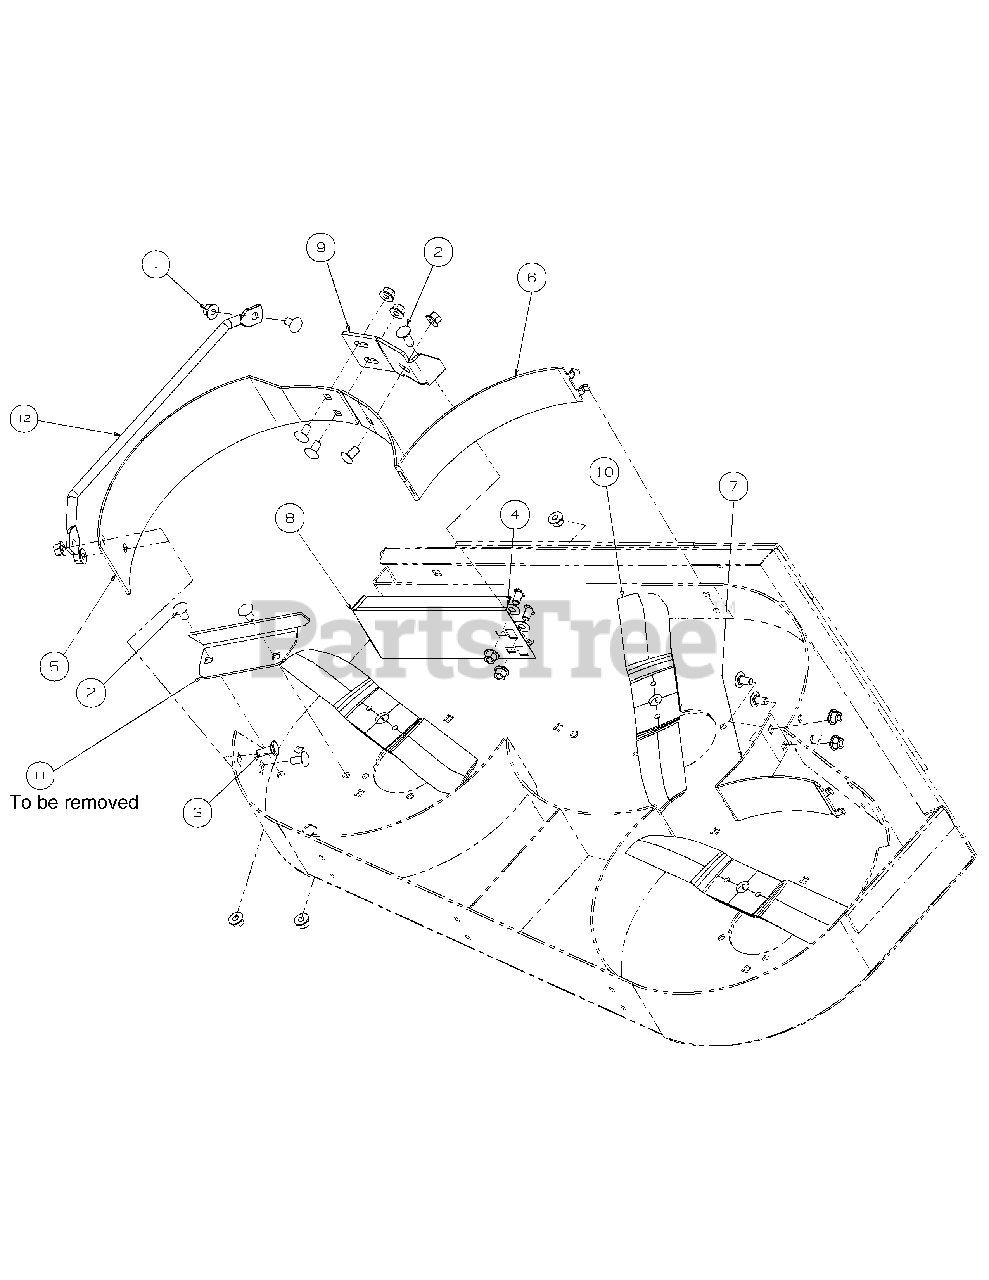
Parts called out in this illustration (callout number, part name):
1	Hex Nut, 3/8-16 Flange Lock
2	Carriage Bolt, 3/8-16 x .75
3	Carriage Bolt, 3/8-16 x 1.00
4	Push Retainer
5	Mulch Baffle, Discharge
6	Mulch Baffle
7	Mulch Baffle, Small
8	Mulch Plug Bracket
9	Mulch Bracket
10	Blade
11	Fabricated Deck, Chute Bracket
12	Fabricated Deck Finger Guard
